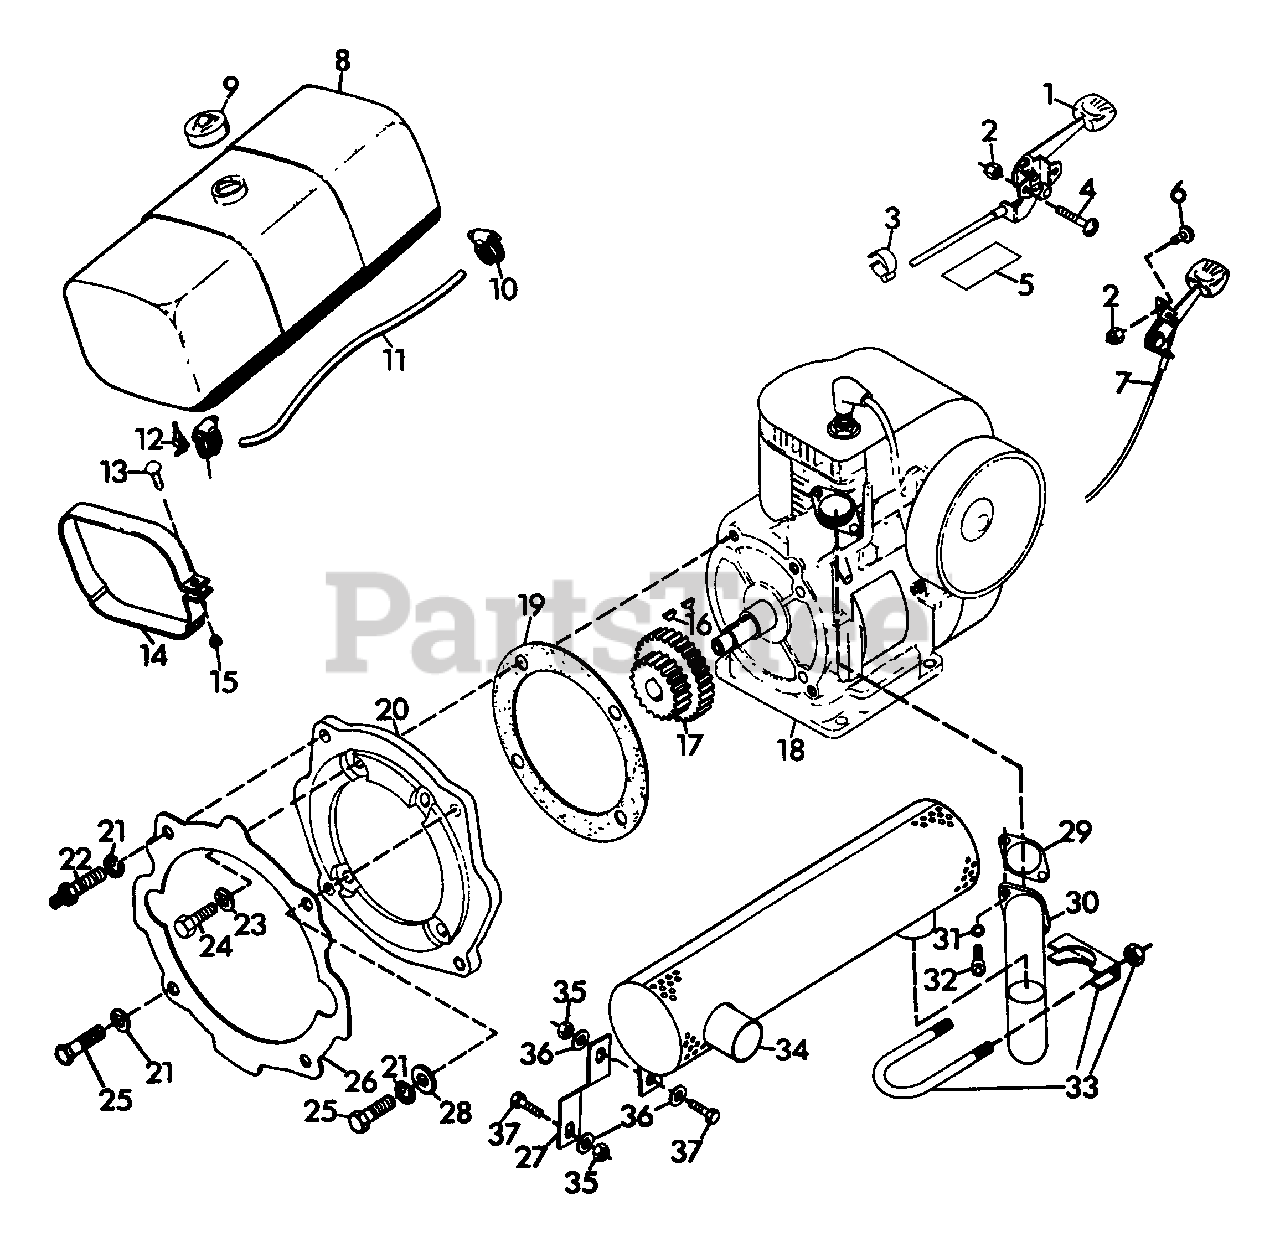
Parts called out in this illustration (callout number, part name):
1	Lever, Throttle Control
2	Nut, Lock 10-24
3	Clip, Conduit
4	Screw, Machine 10-24 x 1.50
5	Decal, Throttle
6	Screw, Machine 10-24 x .50
7	Lever, Choke Control
8	Assembly, Fuel Tank
9	Cap, Fuel Tank
10	Clamp, Hose
11	Line, Fuel
12	Valve and Strainer
13	Bolt, Carriage 1/4-20 x 1.75
14	Strap, Fuel Tank
15	Nut, Lock 1/4-20
16	Key, Woodruff 5/32 x 5/8 Hard #6
17	Gear, 10/12 DP 21/30 Teeth
18	Engine, 16 H.P.
19	Gasket, Engine to Adapter
20	Adapter, Engine
21	Washer, Lock 7/16 SP Heavy
22	Stud
23	Washer, Lock 3/8 SP Heavy
24	Bolt, Hex 3/8-16 x 1
25	Bolt, Hex 7/16-14 x 1.25
26	Gasket, Chassis to Adapter
27	Brace
28	Washer, Flat .469 x .938 x .065
29	Gasket
30	Header, Exhaust
31	Washer, Lock 5/16 Reg.
32	Screw, Cap 5/16-18 x .75
33	Clamp, Muffler
34	Muffler, 16 H.P.
35	Nut, Hex 1/4-20
36	Washer, Flat .312 x .734 x .065
37	Bolt, Hex 1/4-20 x .75
